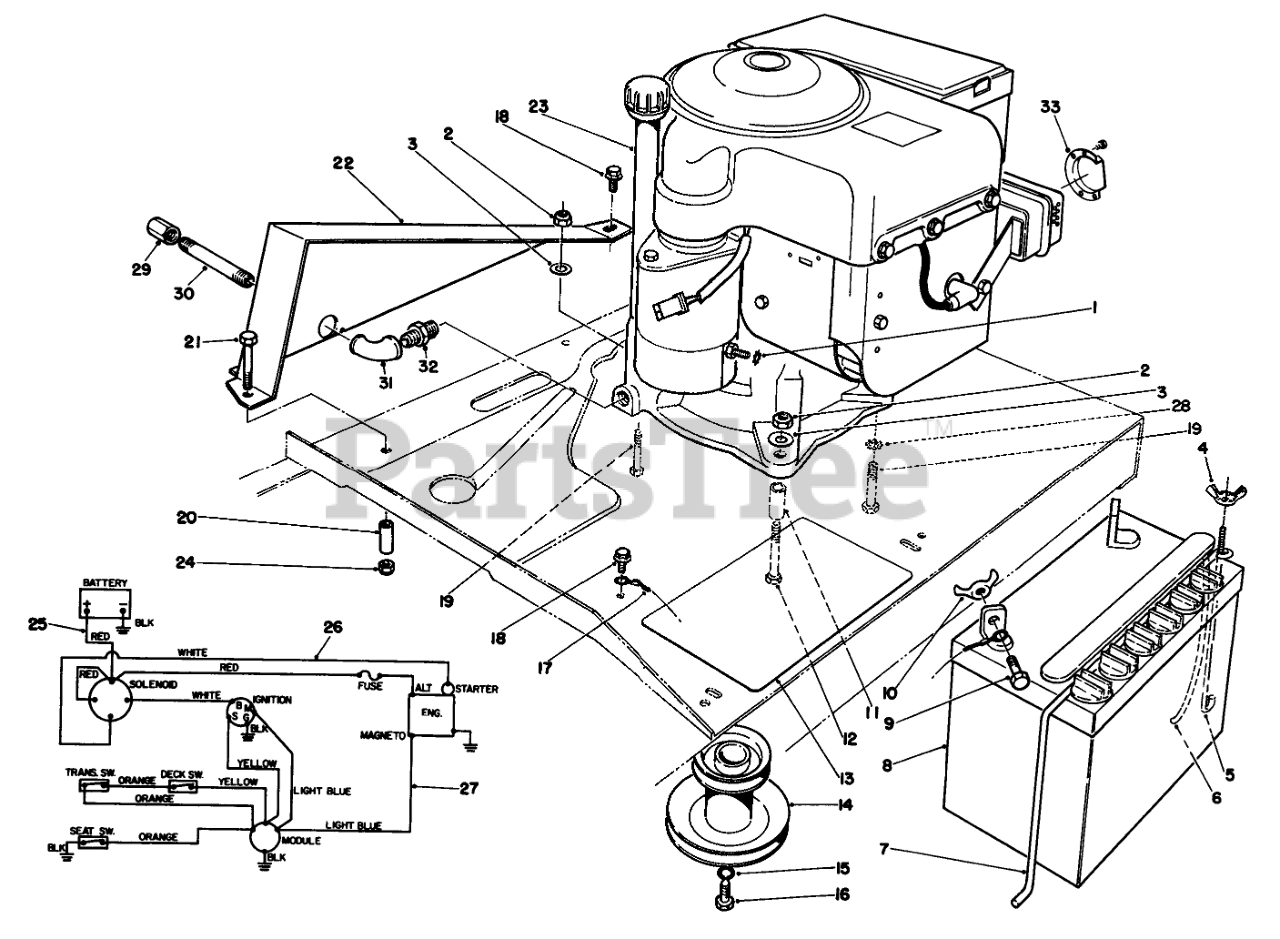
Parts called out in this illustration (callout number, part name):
1	WASHER-LOCK/EXT
2	NUT-HEX, SIDE DEFORM
3	WASHER-PLAIN
4	NUT-WING SPECL
5	POST-BATTERY
6	TUBE-BATT DRAIN/80-2600
7	HOLDDOWN-BATTERY
8	Battery
9	SCREW-HH
10	Nut-Wing
11	SPACER-PIVOT
12	SCREW-HH
13	PAD-SKID, ANTI
14	Pulley-Engine
15	WASHER-FLAT
16	SCREW-HH
17	WIRE ASM(BATT/GRD.
18	SCREW-HWHTF
19	SCREW-HH
20	GUIDE-BELT
21	SCREW-HH
22	Guard-Chain
23	Engine-8 H.P. B & S
24	NUT-LOCK, NI
25	WIRE ASM - BATT TO SOL
26	WIRE ASSEMBLY
27	REAR SCRAPER ASM
28	WASHER-LOCK
29	CAP-PIPE
30	NIPPLE-PIPE
31	ELBOW-STREET
32	BUSHING-PIPE
33	MUFFLER DEFLECTOR
